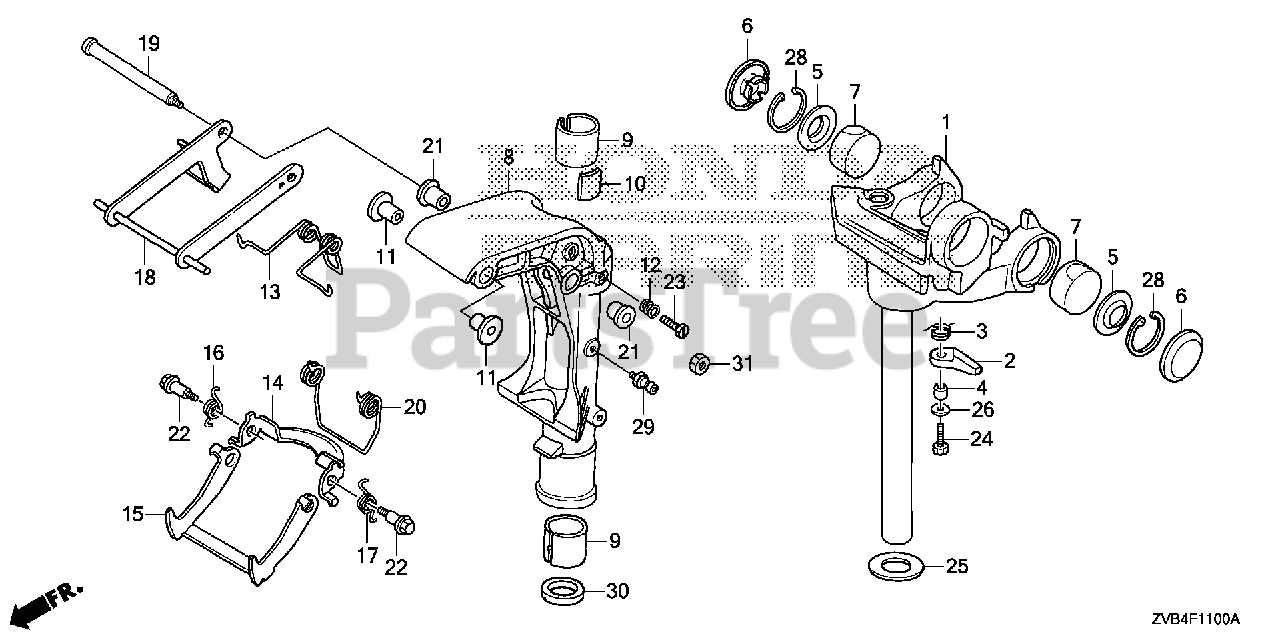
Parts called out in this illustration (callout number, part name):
1	FRAME, MOUNTING *NHB14M* (AQUA MARINE SILVER METALLIC)
2	STOPPER, HANDLEBAR *NHB14M* (AQUA MARINE SILVER METALLIC)
3	SPRING, HANDLE
4	COLLAR, STOPPER
5	WASHER, MOUNT
6	CAP, MOUNTING
7	RUBBER, MOUNTING (UPPER)
8	CASE, SWIVEL *NHB14M* (AQUA MARINE SILVER METALLIC)
9	LINER, SWIVEL CASE
10	BLOCK, FRICTION
11	BUSH, SWIVEL CASE
12	SPRING, FRICTION ADJUSTING
13	SPRING, HOOK RETURN
14	PLATE, REVERSE LOCK
15	HOOK, REVERSE LOCK
16	SPRING, R. REVERSE LOCK
17	SPRING, L. REVERSE LOCK
19	SHAFT, TILT
20	SPRING, REVERSE LOCK
21	BUSH, TILT LEVER
22	BOLT, REVERSE LOCK
23	BOLT, SPECIAL (8X20)
24	BOLT, HEX. (6X20)
25	WASHER, THRUST
26	WASHER, PLAIN (6MM)
27	WASHER, LOCK
28	CIRCLIP (INNER) (40MM)
29	NIPPLE, GREASE
30	OIL SEAL (27.8X33X5) (ARAI)
31	NUT, HEX. (6MM)
